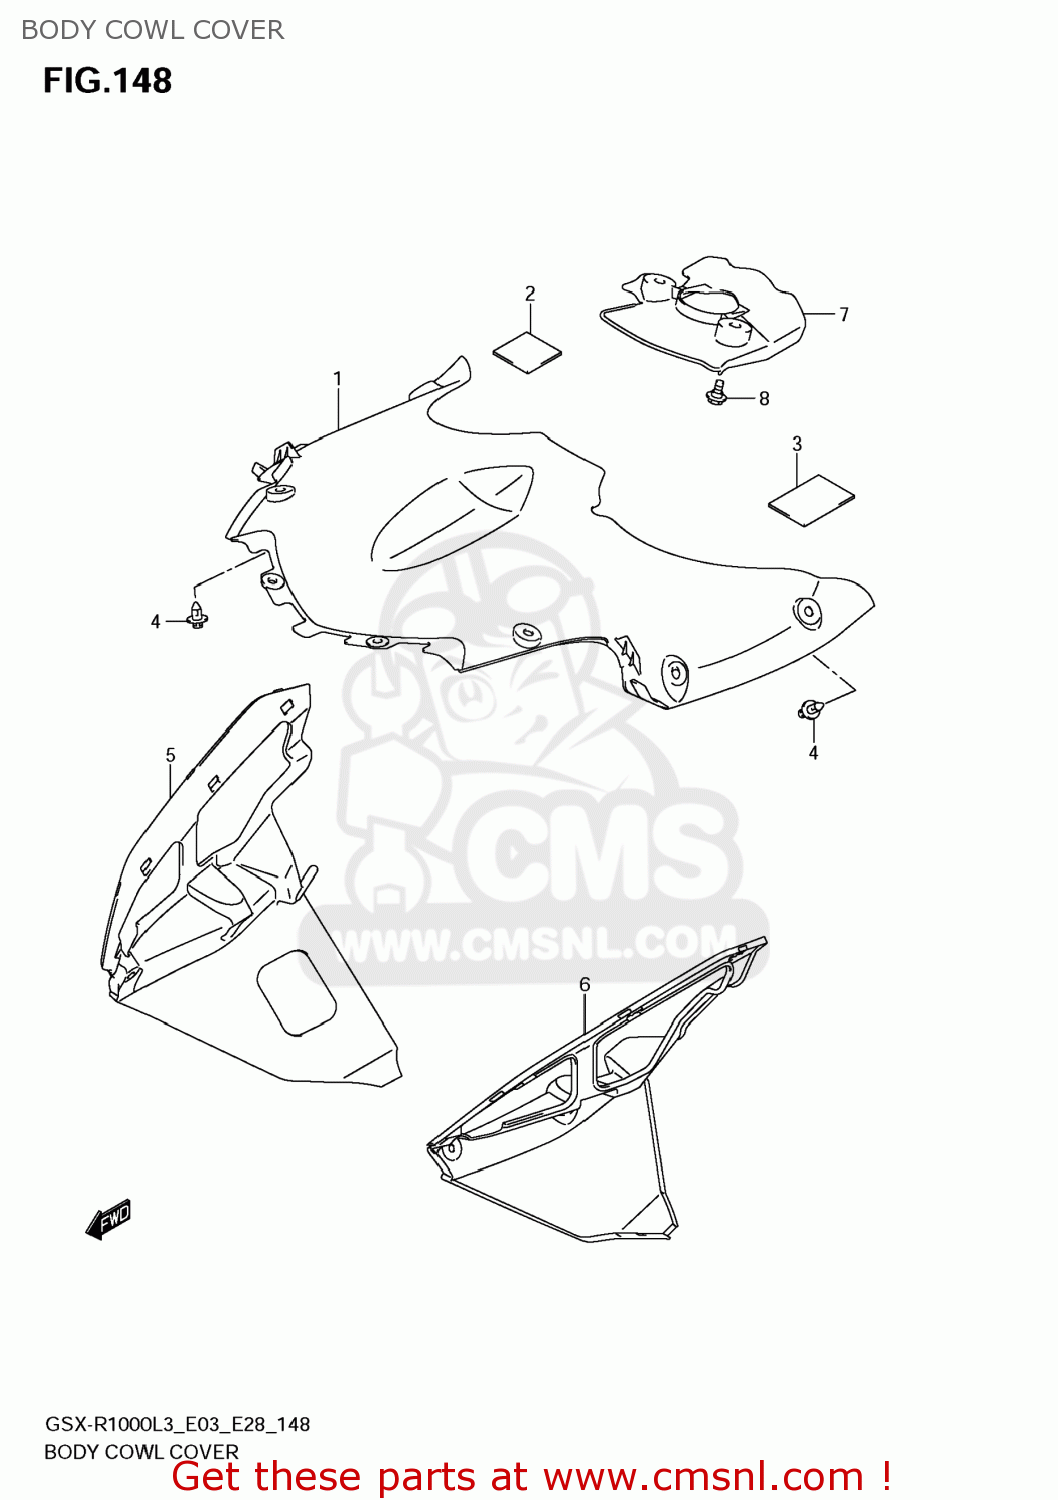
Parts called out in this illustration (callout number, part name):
1	COVER,BODY COWLING
2	PROTECTOR(30X80X1)
3	COVER
4	CLIP(BLACK)
5	COWLING,UNDER INNER,R
6	COWLING,UNDER INNER,L
7	COVER,LWR BRACKET
8	BOLT(6X12)
